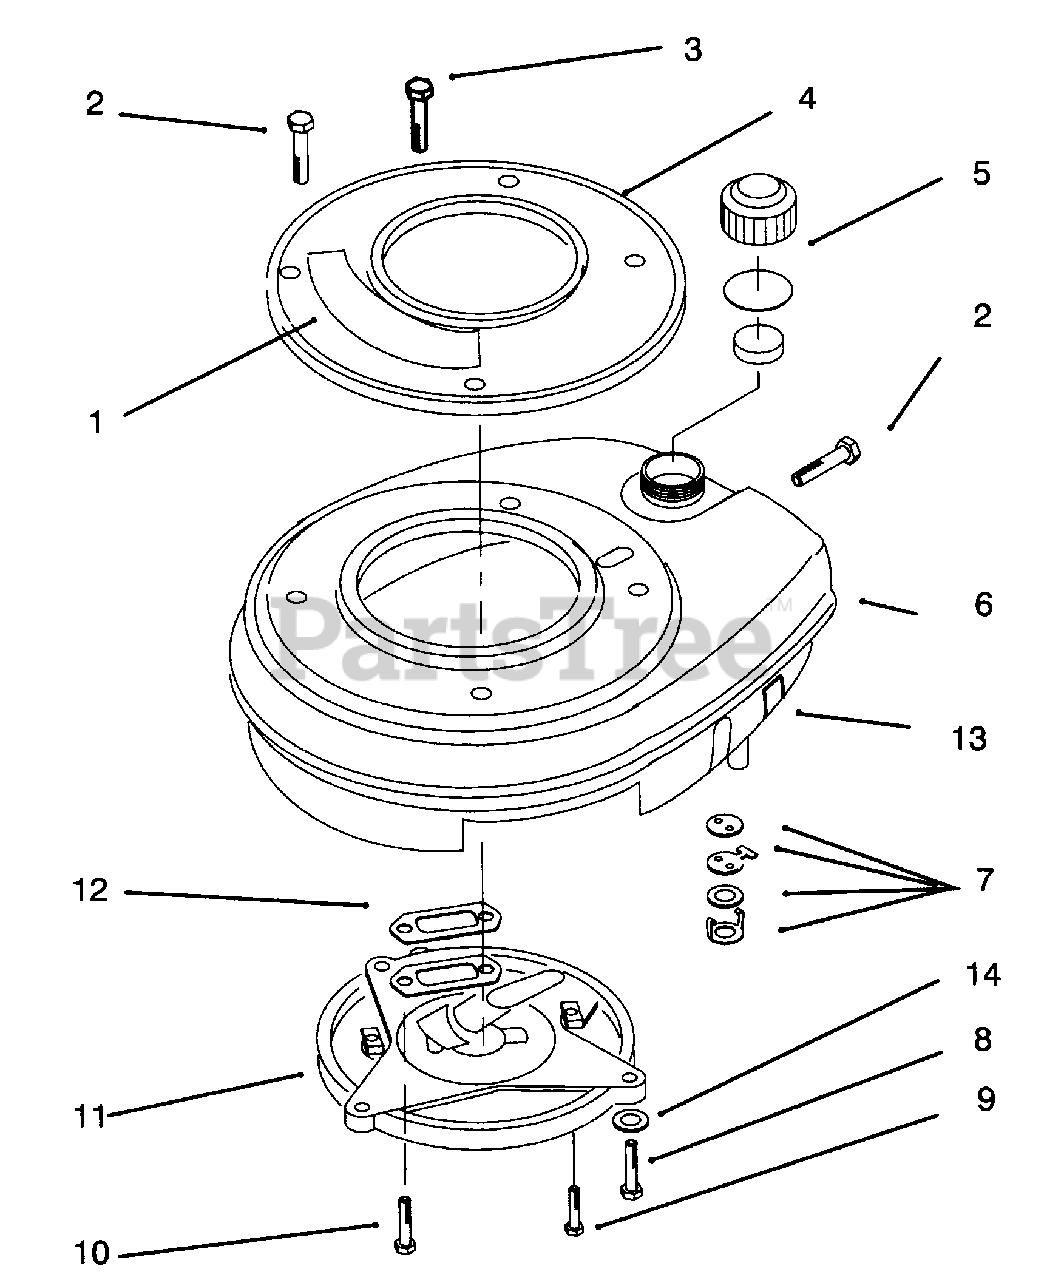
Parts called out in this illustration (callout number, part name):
1	Applique
2	Screw
3	Screw-Starter Mounting
4	Starter Base
5	Fuel Cap (Includes both of the following items)
6	Shroud-Engine
7	Fuel Shut-Off Assembly
8	Screw-Muffler Plt. to Hsg.
9	Screw-Muffler Plt. to Block
10	Screw-Muffler Plt. to Block
11	Plate-Muffler
12	Gasket-Exhaust
13	Decal-Fuel Shut-Off Assy.
14	Washer-Muffler Plt. to Hsg.
